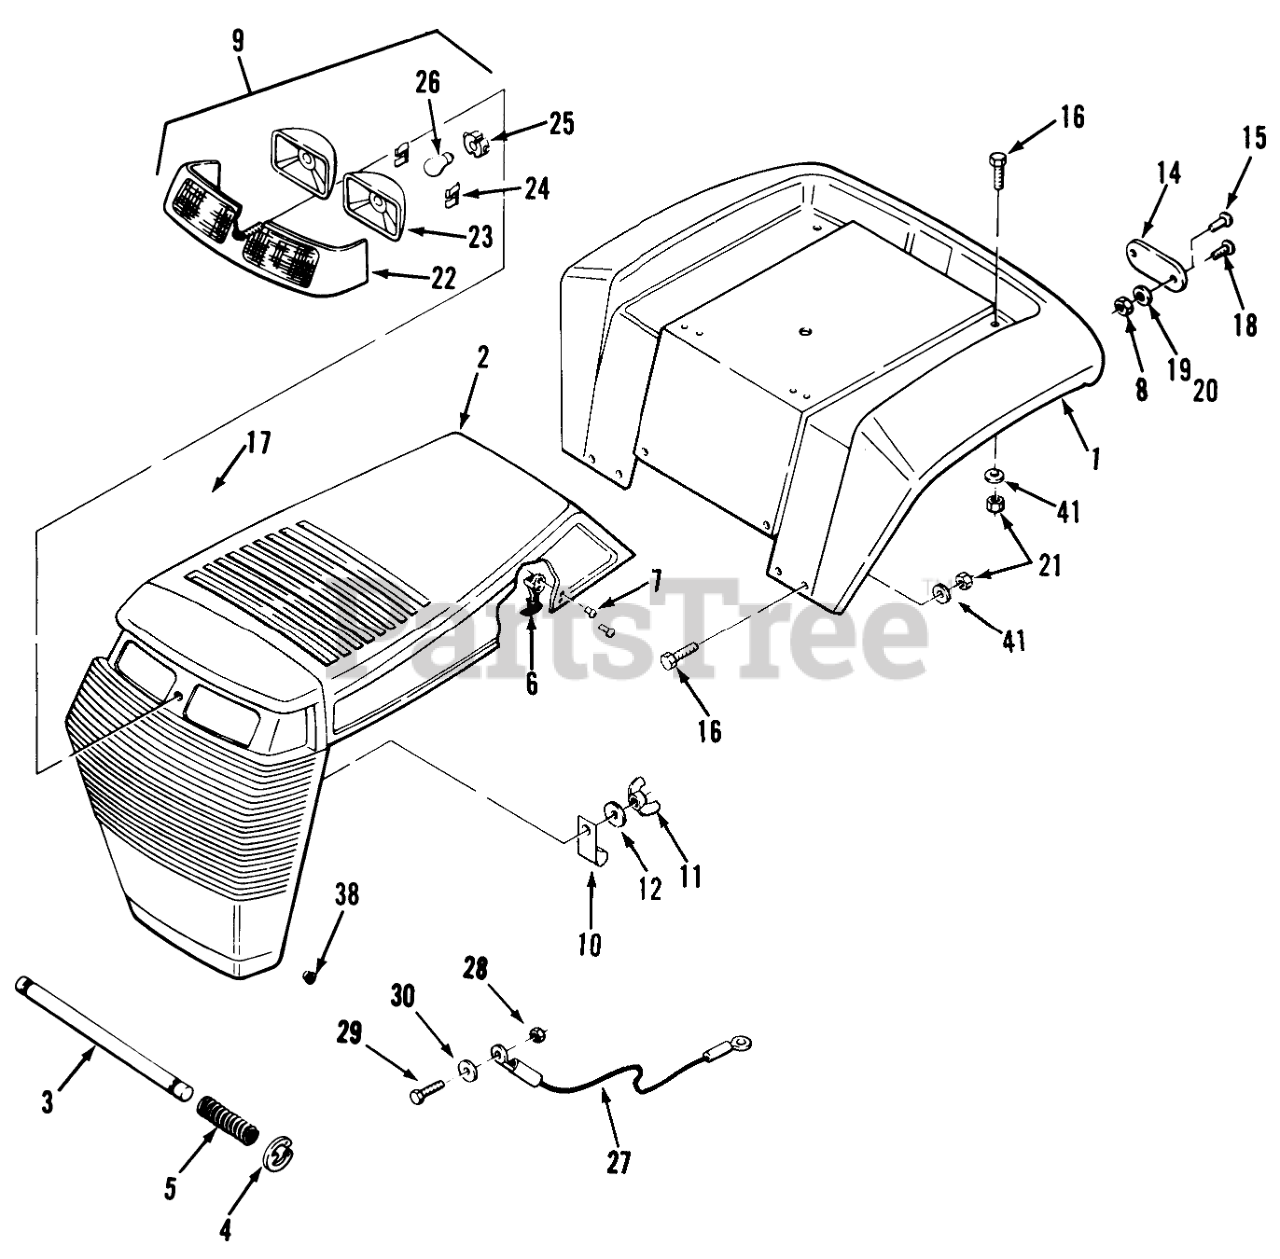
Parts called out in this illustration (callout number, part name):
1	FENDER R
2	Hood & Grill
4	E-Ring
5	SPRING
6	HANDLE ASM
7	RIVET-POP
9	Headlight Bar Assembly (Incl. Ref. #22-24 & 26)
10	J-CLIP
11	WING NUT
12	WASHER
14	Reflector
15	Poprivet
16	SCREW-CARR
17	BUSHING-NYLON 1.093
18	Screw
19	WASHER
20	Lockwasher
21	Nut
22	LIGHT-BAR BLACK
23	LIGHT POD
24	RETAINER
25	SOCKET-HEADLIGHT
26	BULB
27	CABLE-HOOD LANYARD
28	Nut
29	Screw-Machine
30	WASHER-BACKING
38	NYLINER BUSHING
41	Washer-Lock
